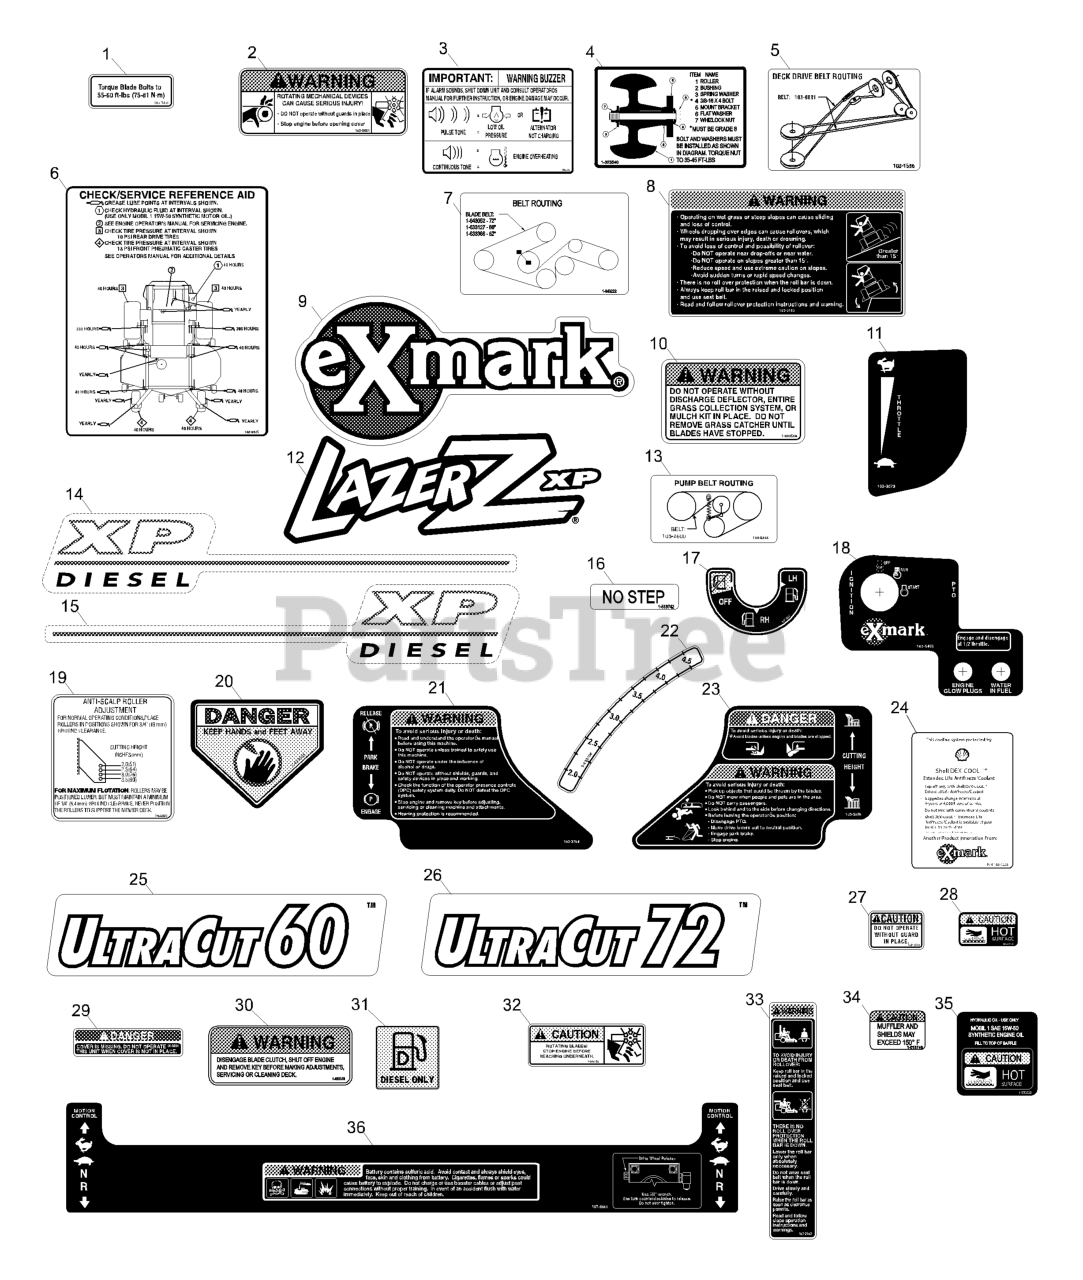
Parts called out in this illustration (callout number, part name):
2	DECAL-DEVICES, ROTATING
3	DECAL-BUZZER, WARNING
4	DECAL,ROLLER MOUNTING
5	DECAL,BELT ROUTING XP
6	DECAL,CHECK/SERVICE XP
7	DECAL,BELT ROUTING
8	DECAL-WARNING
9	DECAL,EXMARK LOGO
10	DECAL-WARNING, DISCHARGE
15	DECAL,XP HOOD RH
16	DECAL,NO STEP
17	DECAL-VALVE, FUEL
18	DECAL,IGNITION/PTO XP
19	DECAL,ANTISCALP
20	DECAL-DANGER
21	DECAL,PARK BRAKE
22	DECAL-HEIGHT, DECK
23	DECAL,CUTTING HEIGHT
24	DECAL,SHELL COOLANT
25	DECAL,ULTRACUT 60
26	DECAL,ULTRACUT 72
27	DECAL-GUARD
28	DECAL-CAUTION
29	DECAL-COVER, MISSING
30	DECAL,WARNING
31	DECAL-FUEL
32	DECAL-FAN, RADIATOR
33	DECAL-WARNING, FOLDING RO
36	DECAL-CONSOLE, TOP
